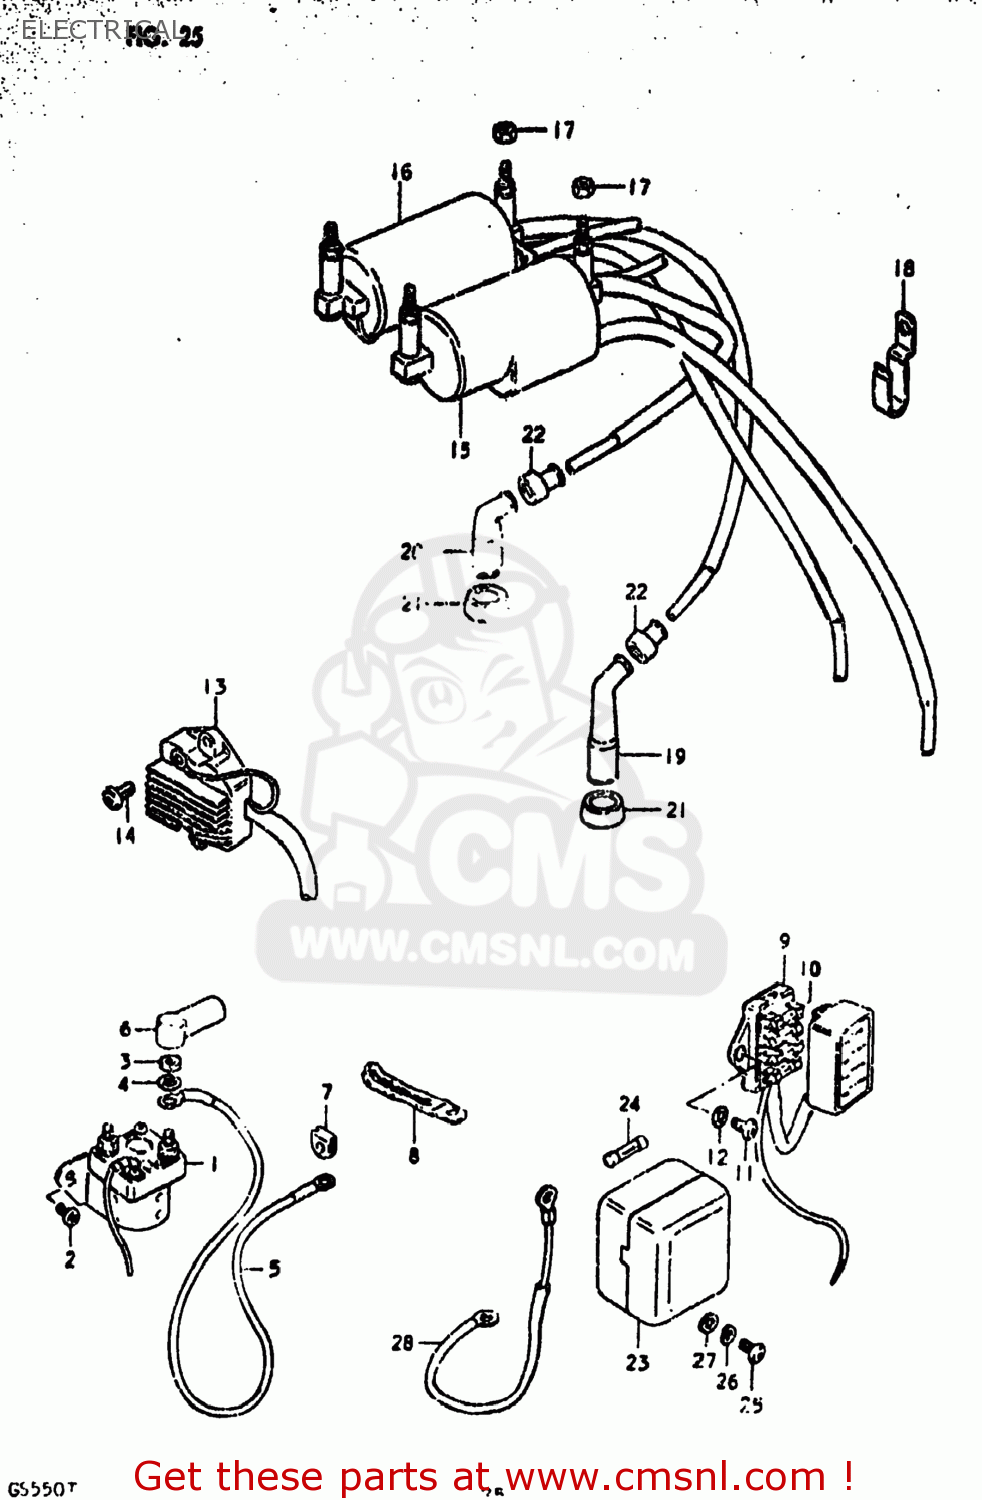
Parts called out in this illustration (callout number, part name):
1	RELAY ASSY,STARTING MOTOR
2	SCREW
3	NUT 6MM
4	LOCK WASHER
5	WIRE,STARTER MOTOR LEAD
6	CAP,STARTER RELAY
7	GROMMET,STARTER CABLE
8	CLAMP
9	BOX ASSEMBLY,FUSE
10	FUSE(15A)
11	SCREW 6X12
12	WASHER
13	RECTIFIER ASSEMBLY
14	SCREW
15	COIL ASSEMBLY,IGNITION
16	COIL ASSEMBLY,IGNITION
17	NUT
18	CLAMP
19	CAP ASSY,SPARK PLUG
20	CAP,SPARK PLUG
21	SEAL,SPARK PLUG
22	SEAL,SPARK PLU
23	TERMINAL ASSEMBLY,POWER SO
24	FUSE(10A)
25	SCREW
26	LOCK WASHER
27	WASHER
28	WIRE,POWER SOURCE LEAD
